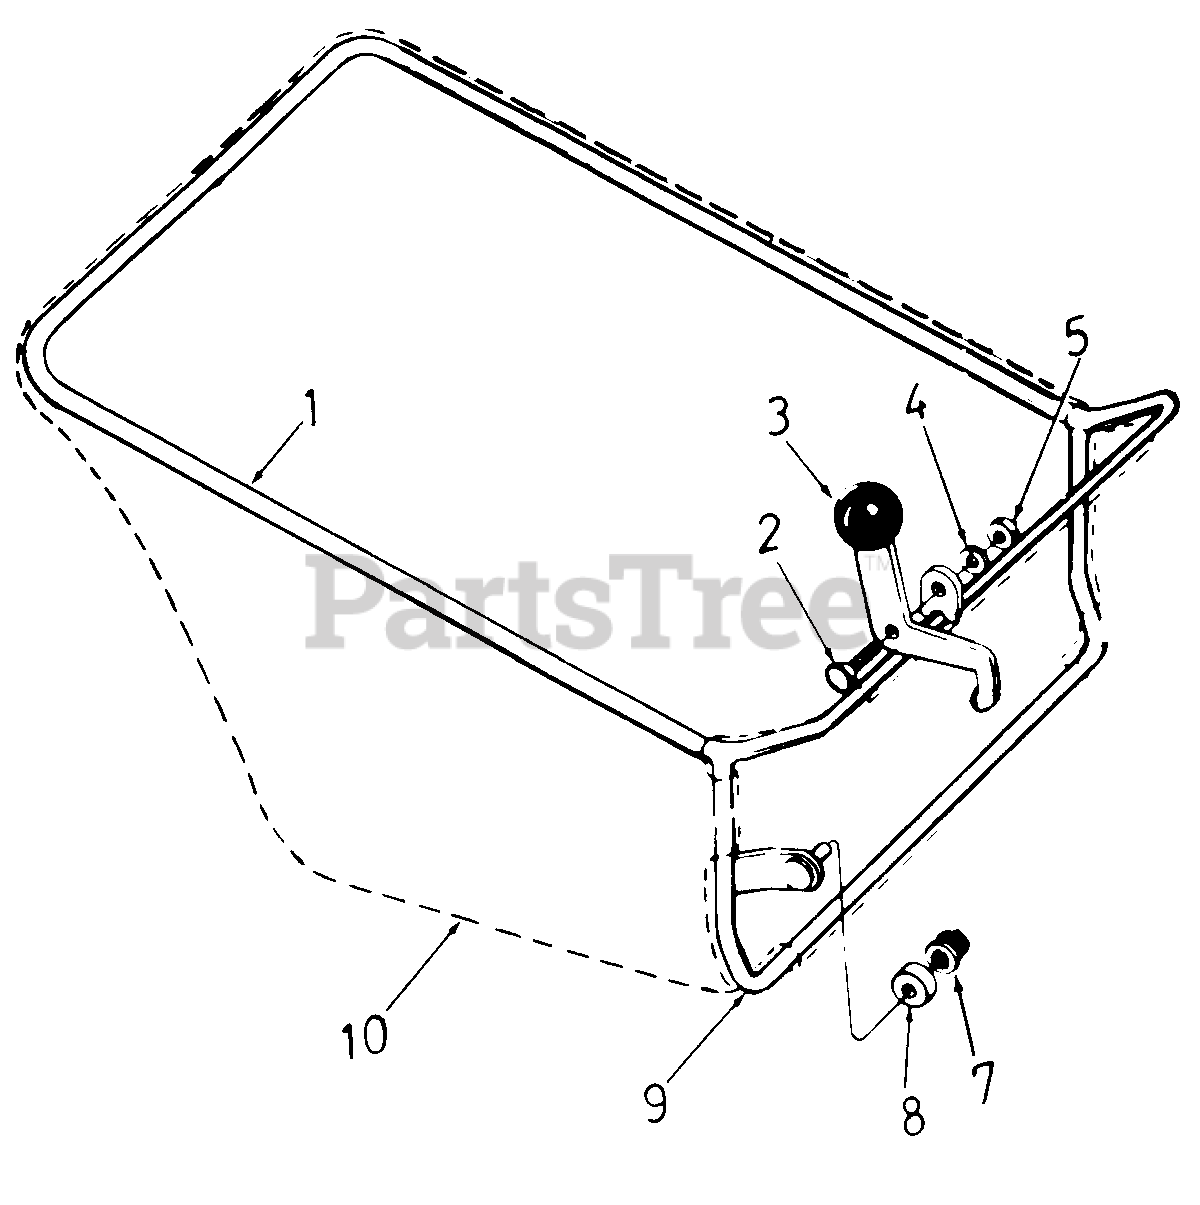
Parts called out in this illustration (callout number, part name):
1	Upper Frame
2	Shld. Scr. .437 Dia. x .180
3	Cam Lever Grip Ass'y.
4	L-Wash. 5/16" Scr.*
5	Hex Nut 5/16-18 Thd.*
7	Push Cap
8	Plastic Roller
9	Lower Frame Ass'y.
10	Grass Bag
